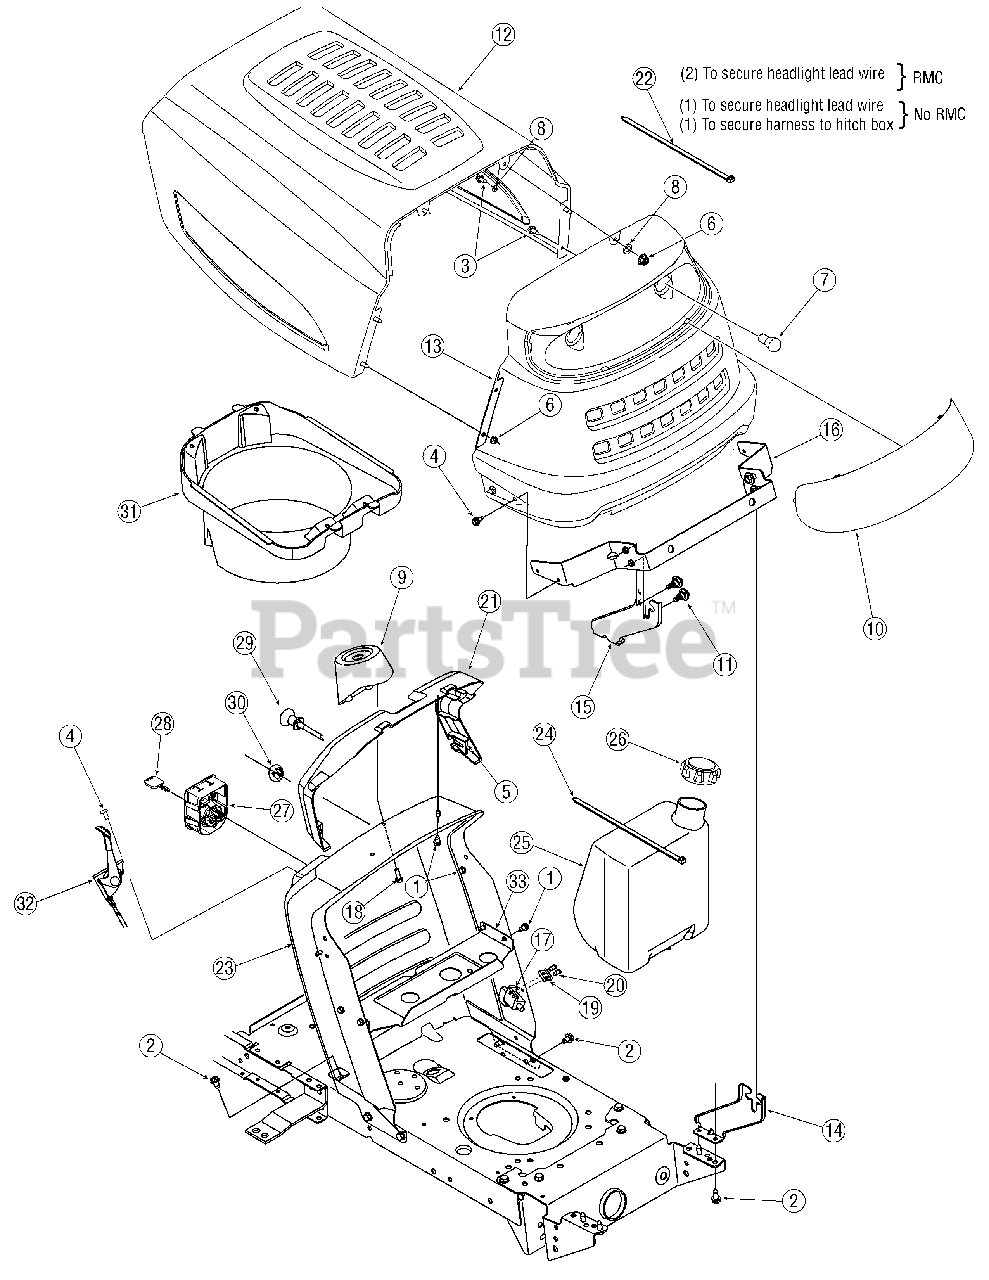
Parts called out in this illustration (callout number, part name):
1	Screw, 1/4-20, 0.500
2	Screw, 5/16-18, 0.625
3	Screw, 1/4-20, .620, Gr5
4	Screw, 1/4-20, .500
5	Nut, 1/4-20, Speed U-type
6	Nut, Flange Lock, 1/4-20, Gr5
7	Headlamp, 12V
8	Washer, Flat, .265 x .938 x .120
9	Support, Steering
10	Lens
11	Screw, Shoulder, .43 x.29, 5/16-18
18	Screw, 1/4-15, 0.750
19	Switch Plate (for models equipped with Reverse Caution Mode)
20	Pop Rivet (for models equipped with Reverse Caution Mode)
21	Collar, Dash
22	Cable Tie
24	Cable Tie, 34.75
25	Fuel Tank, 1.5 gal.
26	Fuel Tank Cap
27	Ignition Switch Module (Reverse Caution Mode - RMC)
27	Igntion Switch (No RMC)
28	Key
29	Choke Control, 37.5"
31	Plenum (Single Cylinder
31	Plenum (Twin Cylinder Engine)
32	Throttle/Choke Control, 25" (Single Cylinder Engine)
32	Throttle Control, 39" (Twin Cylinder Engine)
